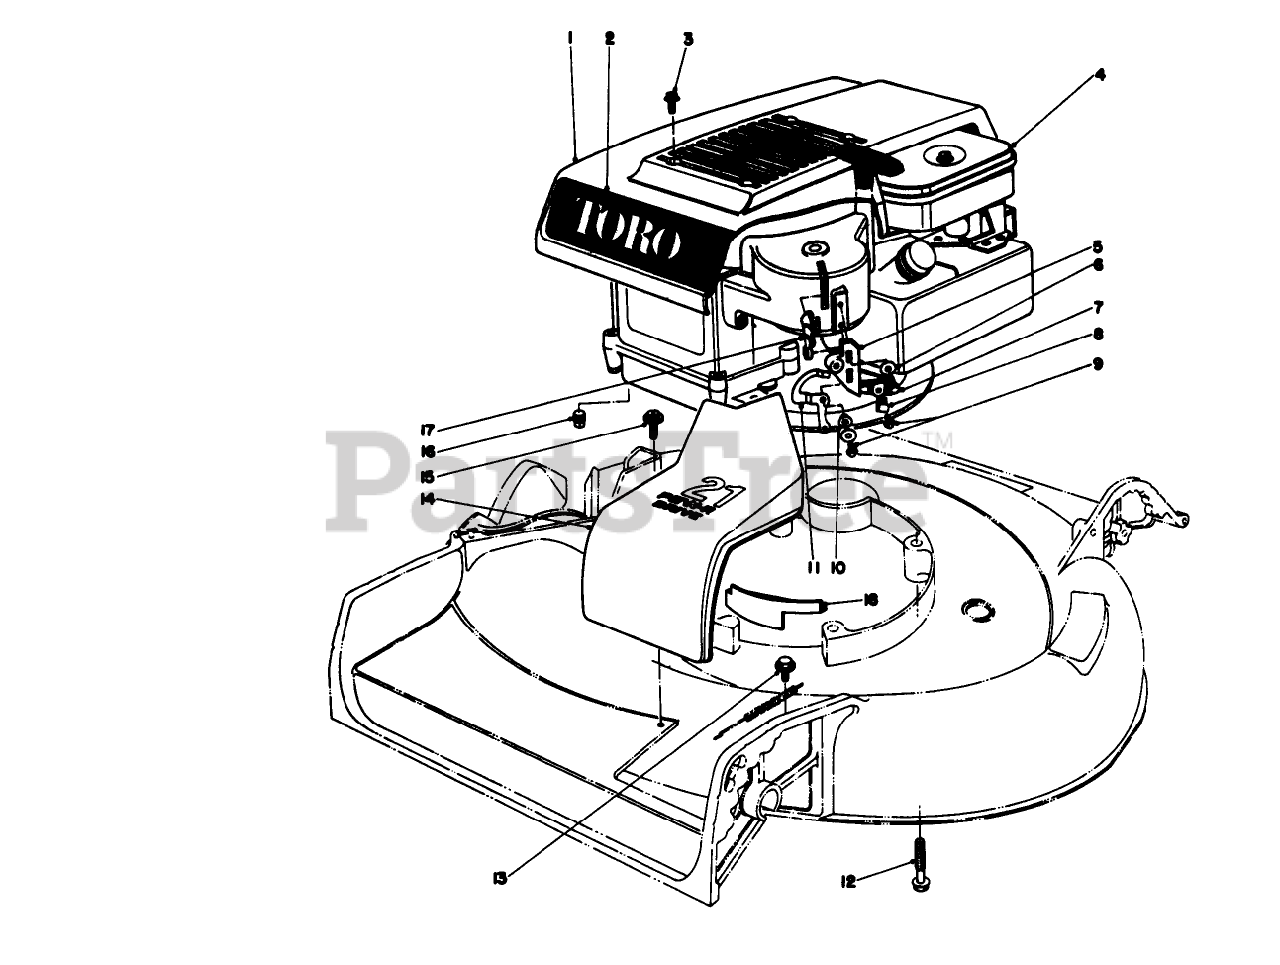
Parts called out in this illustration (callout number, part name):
1	SHROUD
4	Engine
5	Block Cable Pivot
6	WASHER-FLAT
7	SCREW-SHWH
9	SCREW-HWH
10	BUSHING
12	3/8-16 X 2-3/4 CAPSCR
13	SCREW-THD ROLL, HWH
14	BELT DRIVE COVER
15	SCREW
16	PLUG-PIPE, SQH
17	INTERLOCK LEVER
18	HOUSING CAP
